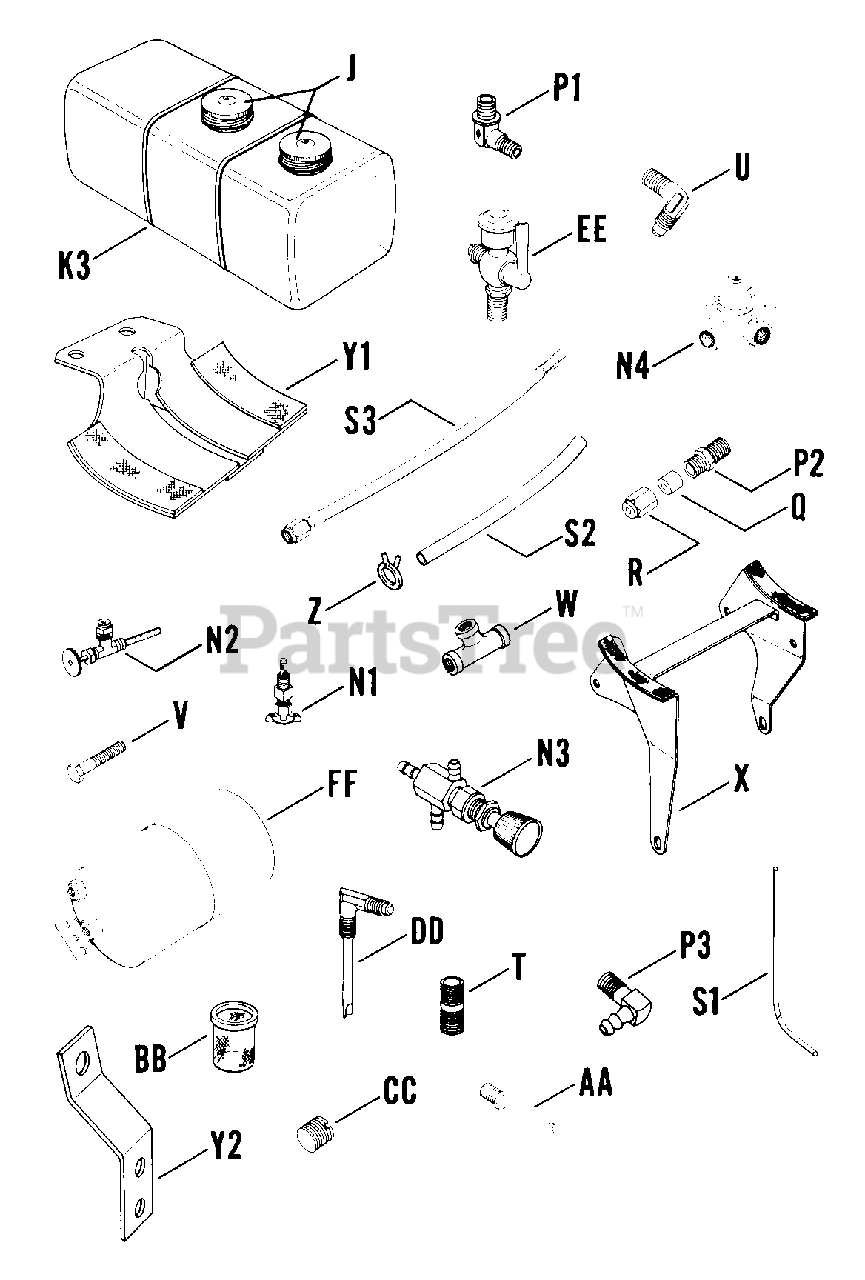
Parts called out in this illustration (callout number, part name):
P3	HOSE - USE 25 155 02
S2	HOSE - USE X-386-25
S2	LINE - USE X-807-2
T	NIPPLE, PIPE 1/8 X 3/4 USE 25 136 23-S
Z	CLAMP HOSE USE X-426-9
